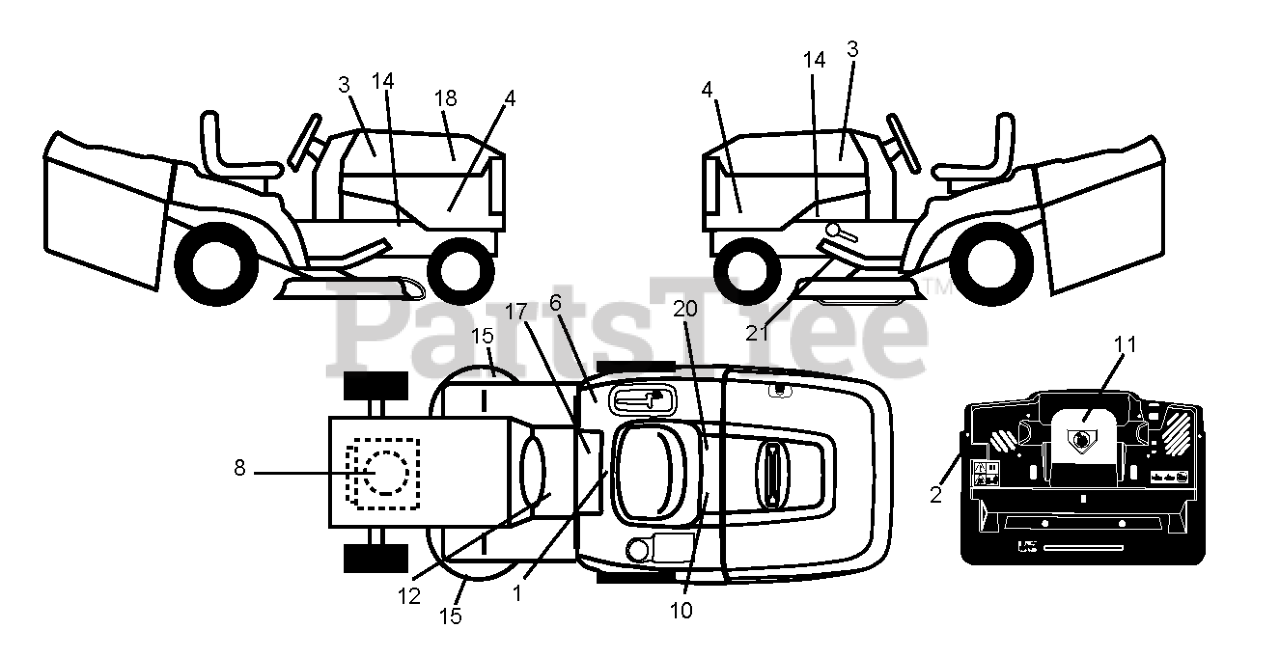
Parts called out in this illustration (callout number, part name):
1	LABEL
2	DECAL
3	DECAL.HOOD.LOGO.ORANGE.HUSQVAR
6	Decal, Fender 100 DB/CE
8	DECAL
10	DECAL BTRY SYMBOLS
11	DECAL.INTERNATIONL.CUTFINGER
12	DECAL
17	DECAL PARK BRAKE
20	DECAL.BYPASS.FENDER.CRD.LT.YT
